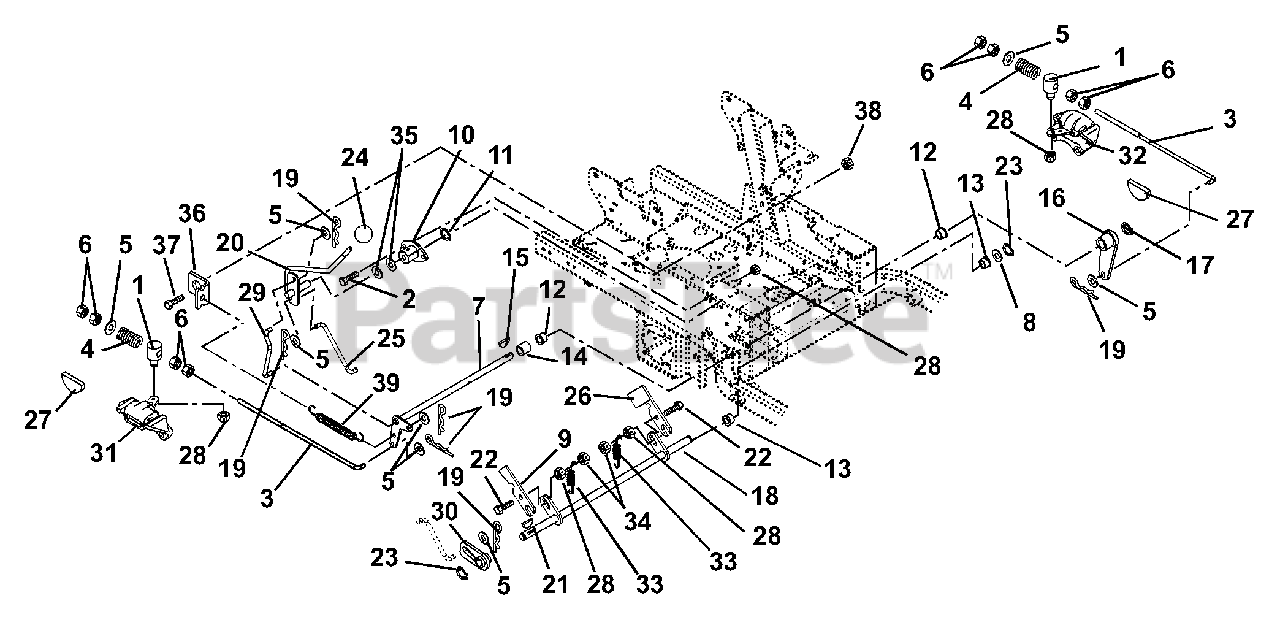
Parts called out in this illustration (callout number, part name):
1	Pivot, Brake Rod
2	Bolt, Hex .31-18 x .75 Grade 5
3	Rod, Brake
4	Spring, Compression .143 x .710 x 2.00
5	Washer, Flat Steel .406 x .812 x .065
6	Nut, Hex .38-16
7	Weldment, Brake Cross Shaft
8	Washer, Flat Steel .505 x 1.00 x .062
9	Slide, Interlocking Brake
10	Bushing, Flange
11	Ring, Retaining External .625 x .05
12	Bushing-Flange .750 x 1.000 x .625 x 1.250
13	Bushing-Flange .515 x .750 x .745 x 1.00 Nylon
14	Bushing, Sleeve .75 X 1.00 X .75
15	Key, Woodruff .19 x .75 Hard #9
16	Weldment, Brake Arm
17	Ring, Retaining External .689 x .078
18	Weldment, Mechanical Brake
19	Pin, Hair
20	Weldment, Brake Actuating
21	Key, Woodruff .13 x .63
22	Bolt, Round Head Square Neck .31-18 x 1.25 Grade 5
23	Ring, Retaining External .50 x .05
24	Knob, Steering Lock
25	Linkage, Brake Actuating
26	Interlock, Safety Switch
27	Pad, Disk Brake
28	Nut, Locking Top Flange .31-18
29	Linkage, Brake Actuating
30	Weldment, Parking Brake Hub
31	Brake, Right Hand Caliper
32	Brake, Left Hand Caliper
33	Spring, Tension .061 x .50 x 3.0
34	Nut, Locking Center .31-18
35	Washer-Flat-Steel .630 x 1.250 x .062
36	Bracket, Spring Mounting
37	Bolt, Hex .50-13 x 1.00 Grade 5
38	Nut, Locking Top Flange .50-13
39	Spring, Extension
